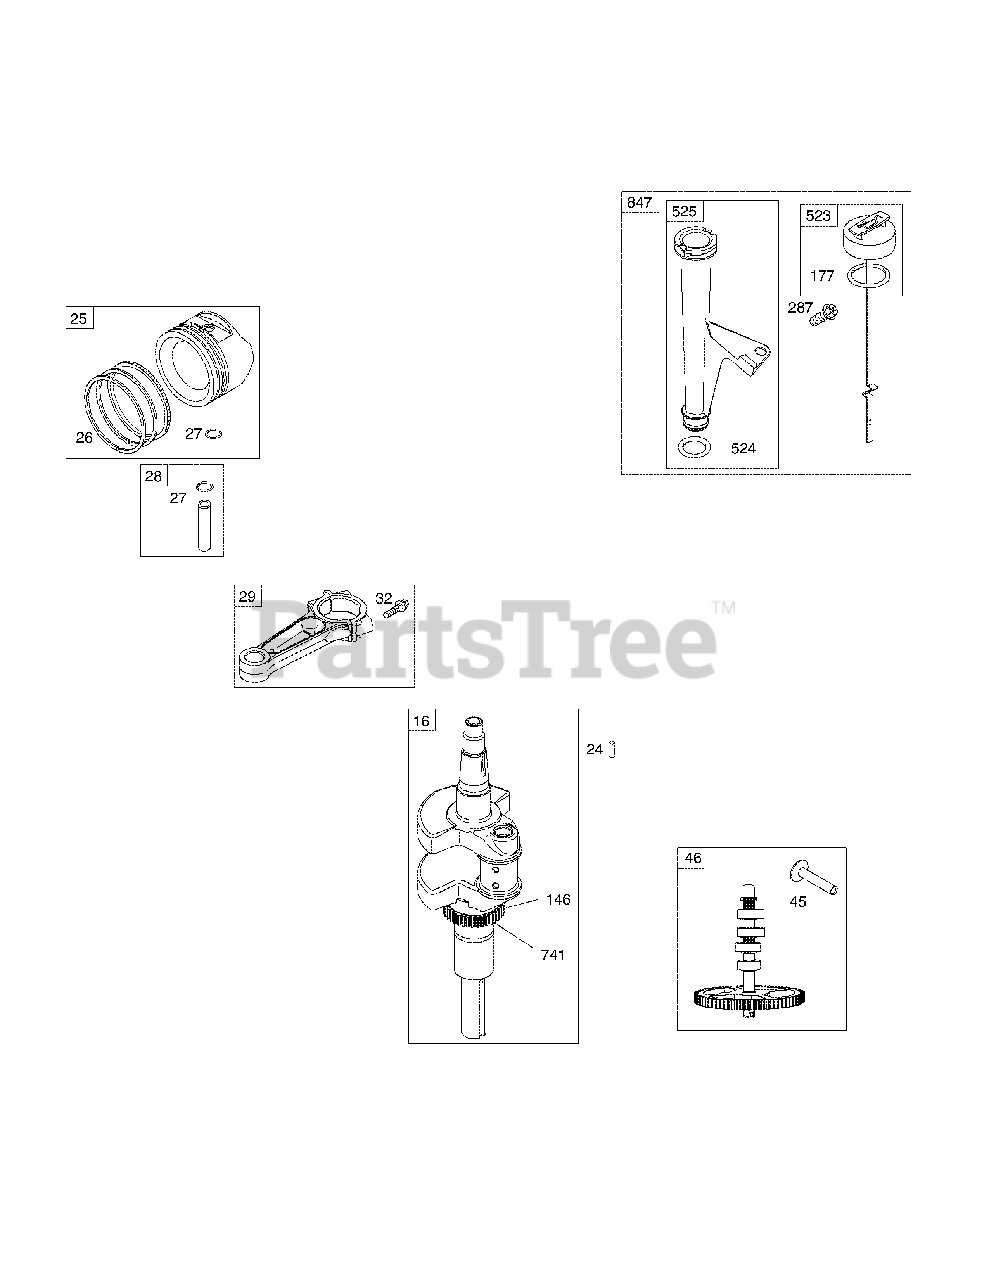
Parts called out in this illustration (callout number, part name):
1	Cylinder Assembly
2	Kit-Bushing/Seal (Magneto Side)
3	Oil Seal (Magneto Side)
4	EngineSump
5	Cylinder Head (Cylinder #1)
5A	Cylinder Head (Cylinder #2)
7	Cylinder Head Gasket
8	Breather Assembly
9	Breather Gasket
10	Screw (Breather Assembly)
11	Breather Tube
12	Crankcase Gasket
13	Screw (Cylinder Head)
15	Oil Drain Plug
16	Crankshaft
20	Oil Seal (PTO Side)
22	Screw (Crankcase Cover/Sump)
23	Flywheel
24	Flywheel Key
25	Piston Assembly (Standard)
25	Piston Assembly (.020" Oversize)
26	Ring Set (Standard)
26	Ring Set (.020" Oversize)
27	Piston Pin Lock
28	Piston Pin
29	Connecting Rod
32	Screw (Connecting Rod)
33	Exhaust Valve
34	Intake Valve
35	Valve Spring (Intake)
36	Valve Spring (Exhaust)
40	Valve Retainer
42	Valve Keeper
45	Valve Tappet
48	Short Block
50	Intake Manifold
51	Intake Gasket
51A	Intake Gasket
53	Stud (Carburetor)
54	Screw (Intake Manifold)
73	Rotating Screen
74	Screw (Rotating Screen)
75	Washer (Flywheel)
95	Screw (Throttle Valve)
98	Idle Speed Kit
104	Float Hinge Pin
105	Float Needle Valve
108	Choke Valve
117	Main Jet (Standard) (Left Jet)
117A	Main Jet (Standard) (Right Jet)
118	Main Jet (High Altitude) (Left Jet)
118A	Main Jet (High Altitude) (Right Jet)
121	Carburetor Overhaul Kit
125	Carburetor
130	Throttle Valve
131	Throttle Shaft Kit
133	Carburetor Float
135	Fuel Transfer Tube
137	Float Bowl Gasket
141	Choke Shaft Kit
142	Carburetor Nozzle
146	Timing Key
150	Nozzle Gasket
163	Air Cleaner Gasket
165	Nut (Ring Gear)
177	O-Ring Seal (Dipstick)
187	Fuel Line (Cut to Required Length)
188	Screw (Control Bracket)
192	Rocker Arm Adjuster
197	Screw (Back Plate)
209	Governor Spring (Yellow/Black)
211	Governed Idle Spring (Orange)
212	Throttle Link
216	Choke Link
217	Choke Return Spring
219	Governor Gear
220	Washer (Governor Gear)
221	Governor Cup
222	Control Bracket
227	Governor Control Lever
231	Screw (Choke Valve)
239	Oil Pressure Switch
240	Fuel Filter
250	Breather Retainer
252	Oil Collector
265	Casing Clamp
267	Screw (Casing Clamp)
276	Sealing Washer (Fuel Solenoid)
278	Washer (Governor Control Lever)
287	Screw (Dipstick Tube)
304	Blower Housing
305	Screw (Blower Housing)
305A	Screw (Blower Housing to Intake Elbow)
306	Cylinder Shield (Cylinder #2)
307	Screw (Cylinder Shield) (1.4-20 x 2.3)
309	Starter Motor
310	Screw (Starter Motor)
332	Nut (Flywheel)
333	Magneto Armature
334	Screw (Magneto Armature)
337	Spark Plug
358	Engine Gasket Set
385	Screw (Fuel Pump)
387	Fuel Pump
404	Washer (Governor Crank)
415	Plug (Oil Pressure Switch)
418	Carburetor Plate
431	Intake Elbow
445	Air Cleaner Cartridge Filter
447	Screw (Air Guide Cover) 10-24 x 7.16)
447A	Screw (Air Guide Cover)
467	Air Cleaner Knob
474	Alternator
501	Regulator
503	Starter Strap
505	Nut (Governor Control Lever)
510	Starter Drive
513	Drive Clutch
523	Dipstick
524	Dipstick Tube Seal
525	Dipstick Tube
526	Screw (Regulator)
544	Starter Armature
552	Governor Crank Bushing
552A	Governor Crank Bushing
562	Screw (Governor Control Lever)
573	Back Plate
579	Nut (Starter Cable)
601	Hose Clamp (Black)
601A	Hose Clamp (Green)
615	Governor Shaft Retainer
616	Governor Crank
617	O-Ring Seal (Intake Manifold) (Red)
628	Screw (Fuel Pump Bracket)
633	Choke Seal/Throttle Shaft
635	Spark Plug Boot
654	Nut (Carburetor)
668	Spacer (Rotating Screen)
668A	Spacer (Rotating Screen)
672	Carburetor Plate Gasket
691	Governor Shaft Seal
695	Screw (Ring Gear)
697	Screw (Drive Cap)
718	Locating Pin
741	Timing Gear
742	E-Ring Retainer (Governor Crank)
750	Screw (Oil Pump Cover)
783	Pinion Gear
788	Fuel Pump Bracket
789	Wiring Harness
798	Screw (Rocker Arm)
803	Starter Housing
847	Dipstick/Tube Assembly
851	Spark Plug Terminal
865	Air Guide Cover (Cylinder #1)
865A	Air Guide Cover (Valley)
868	Valve Seat
877	Alternator Wire/Connector
877A	Alternator Wire/Connector
883	Exhaust Gasket
914	Screw (Rocker Cover)
918	Vacuum Hose
943	O-Ring Seal (Oil Pump Cover)
947	Fuel Solenoid
965	Oil Pump Cover
967	Pre-Cleaner Filter
968	Air Cleaner Cover
975	Float Bowl
987	Throttle Shaft Seal
1005	Flywheel Fan
1013	Oil Filter Nipple
1017	Oil Pump Screen
1022	Rocker Cover Gasket
1023	Rocker Cover (Cylinder #1)
1023A	Rocker Cover (Cylinder #2)
1026	Push Rod (Exhaust)
1026A	Push Rod (Intake)
1027	Oil Filter
1029	Rocker Arm
1036	Emissions Label
1040	Trim Plate
1051	Retaining Ring (Starter Drive)
1058	Operator's Manual
1059	Screw/Washer Kit (Alternator)
1070	Screw (Flywheel Fan)
1090	Brush Retainer
1095	Valve Gasket Set
1100	Rocker Arm Pivot
1119	Screw (Alternator)
1124	O-Ring Seal (Fuel Transfer Tube)
1124A	O-Ring Seal (Fuel Transfer Tube)
1126	Screw (Fuel Transfer Tube)
1127	Screw (Fuel Bowl)
1128	Screw (Carburetor Nozzle)
1169	Screw (Carburetor Plate)
1329	Replacement Engine
